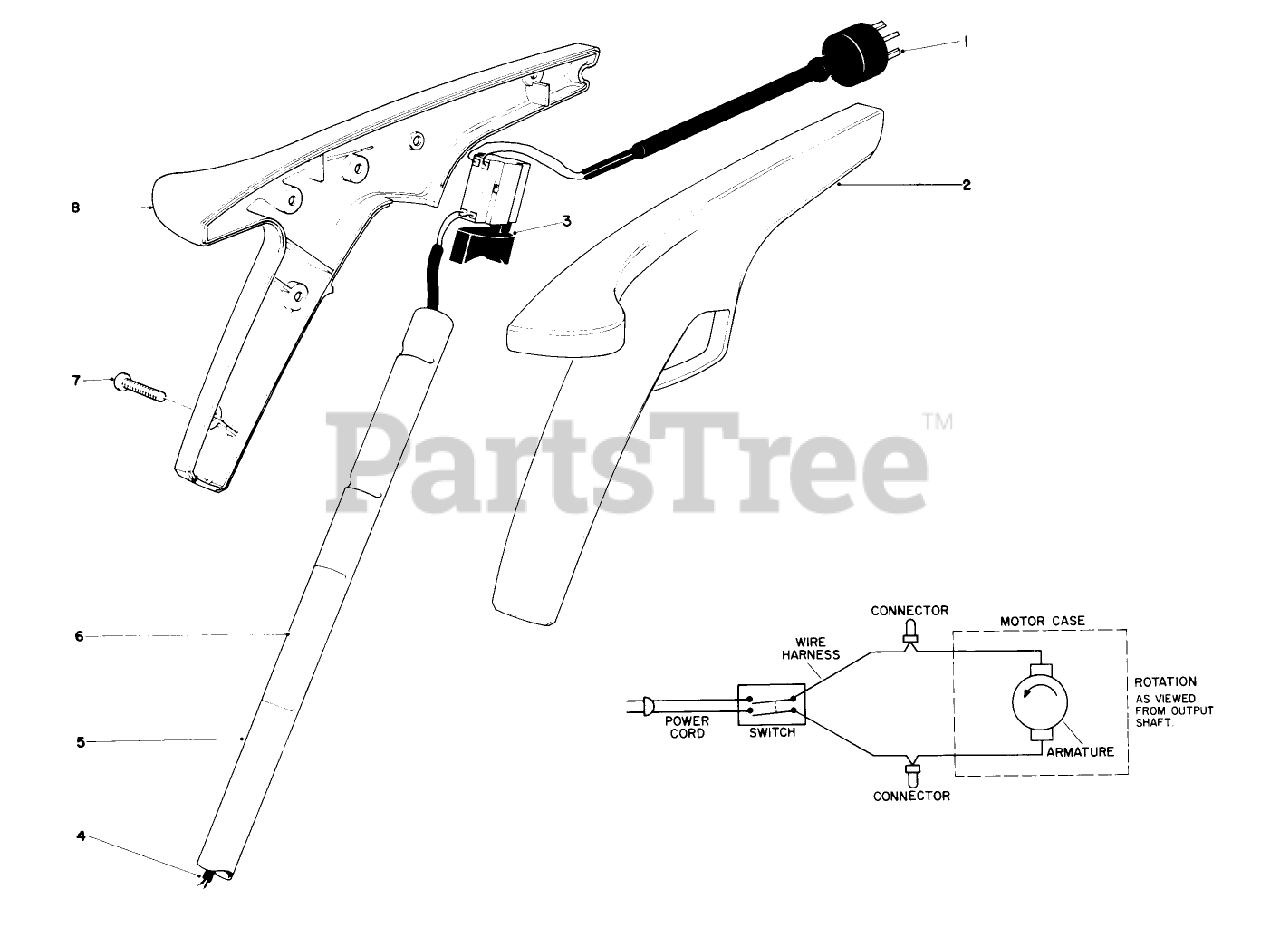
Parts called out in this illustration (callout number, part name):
1	Wiring Harness-Upper
2	LH HANDLE GRIP
3	SWITCH SINGLE SPEED
4	Wiring Harness
5	Handle Tube
6	Decal-Caution
8	Grip-Right Hand
